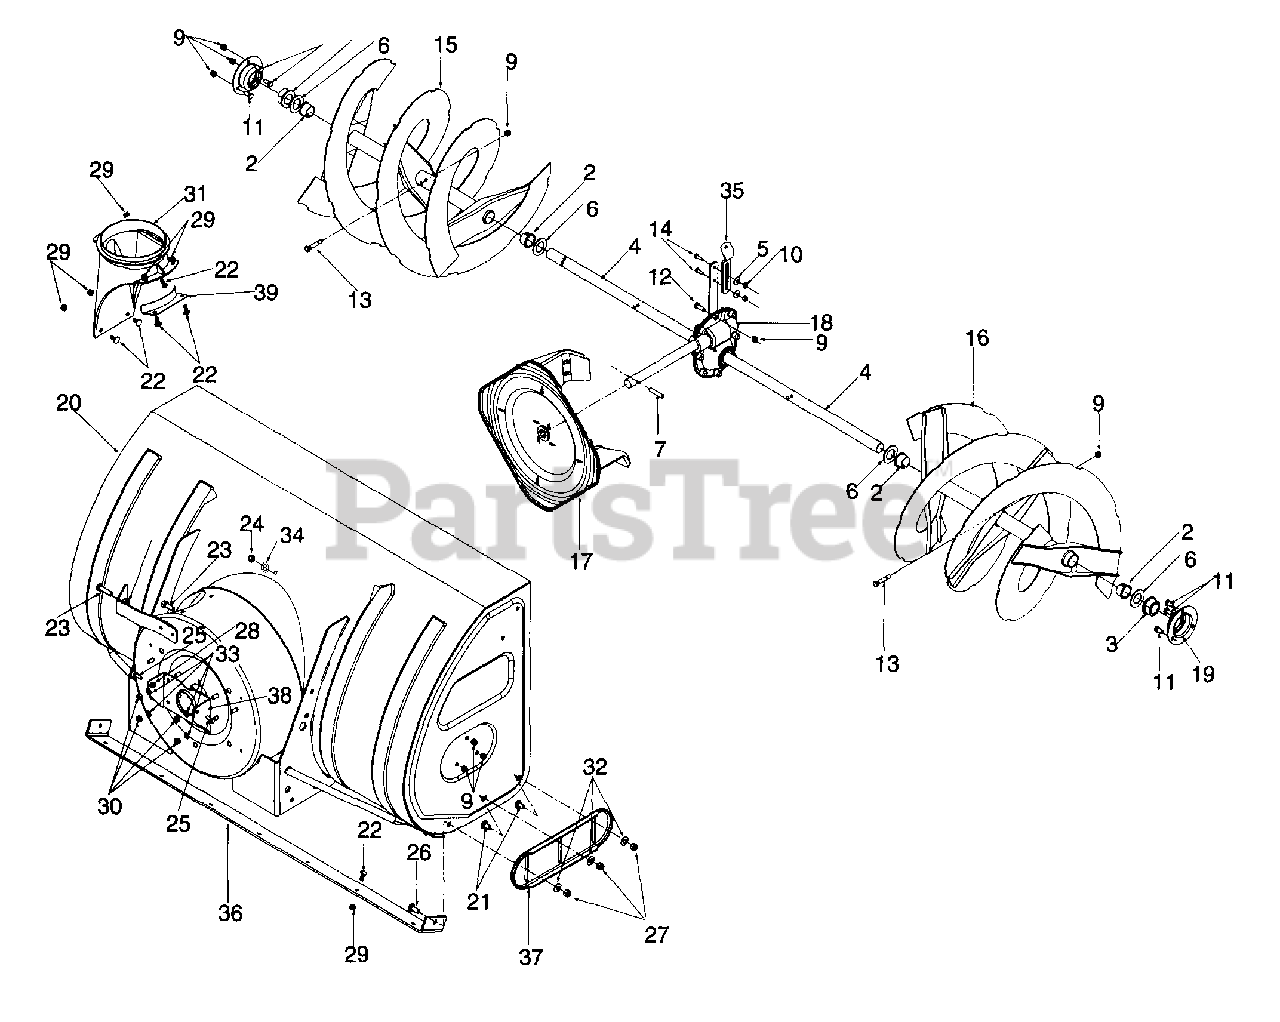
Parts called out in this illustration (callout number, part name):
2	BUSH:FLG:1.05 ID X 1.16 OD
3	BRG:FLG:W/FLATS
4	SPIRAL AXLE 1.00 X 44.12
5	WASH:BELL:.265 X.75 X .062
6	FL-WASH 1.00 ID X 1.75 OD X .1
7	SPRING PIN SPIR 5/16 DIA X 1.7
9	NUT:HX:5/16-18:GRC:LOCK
10	NUT:1/4-28:GRA:HX
11	HHCS:5/16-18:.625:GR5:STD
12	HHCS:5/16-18:.75:GR5:STD
13	SHEAR BOLT 5/16 - 18 X 1-3/4
14	HHCS:1/4-28:.75:GR5:STD
18	GEAR ASM:AUGER
22	BOLT:CAR:5/16-18:.75
23	HHCS:3/8-16:1.50:GR5:STD
24	SCR:AB:5/16-12:0.750:HXINDWSH
25	HHCS:1/4-20:.75:GR5:STD
26	BOLT:CARR:3/8-16
27	NUT:HX:3/8-16:GRC:LOCK
28	NUT:HX:1/4-20:GRC:LOCK
29	NUT:HX:5/16-18:GRC:LOCK
30	NUT:5/16-18:GRB:HX
31	CHUT:ADAP:6" DIA
32	WASH:SPR:.401 X .870 X .063
33	WASH:LOCK:5/16:REGULAR DUTY
34	WASH:BELVL:.340 ID X .872 OD
